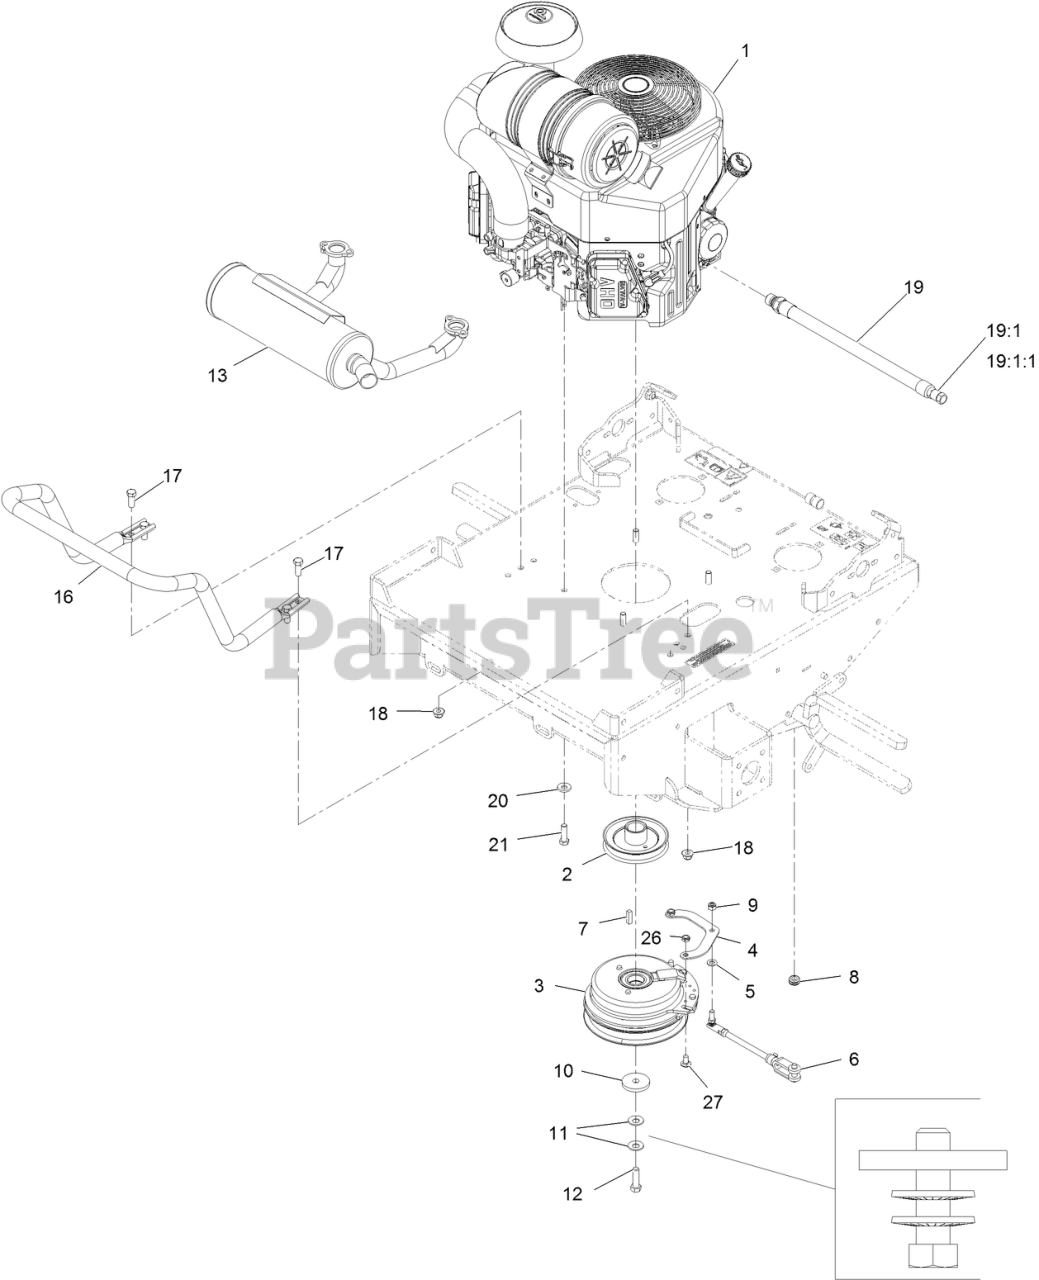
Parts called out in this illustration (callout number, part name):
2	SHEAVE W/ HUB
3	CLUTCH, 200 FT/LBS, 1.13
4	STRAP, CLUTCH
5	WASHER-PLAIN
6	ASM, CLUTCH ANCHOR
7	KEY
8	GROMMET
9	NUT-LOCK
10	WASHER-CLUTCH
11	WASHER-SPRING
12	BOLT-HEX, TAP
13	MUFFLER,HORIZONTAL
16	TUBE-GUARD MUFFLER
17	SCREW-HH
18	NUT-HF, NI
19	ASM, ENGINE OIL DRAIN HOS
19:1	PLUG-HH
19:1:1	O-RING
20	WASHER-BELLEVILLE
21	SCREW-HH
26	NUT-LOCK, NI
27	SCREW-CARR
